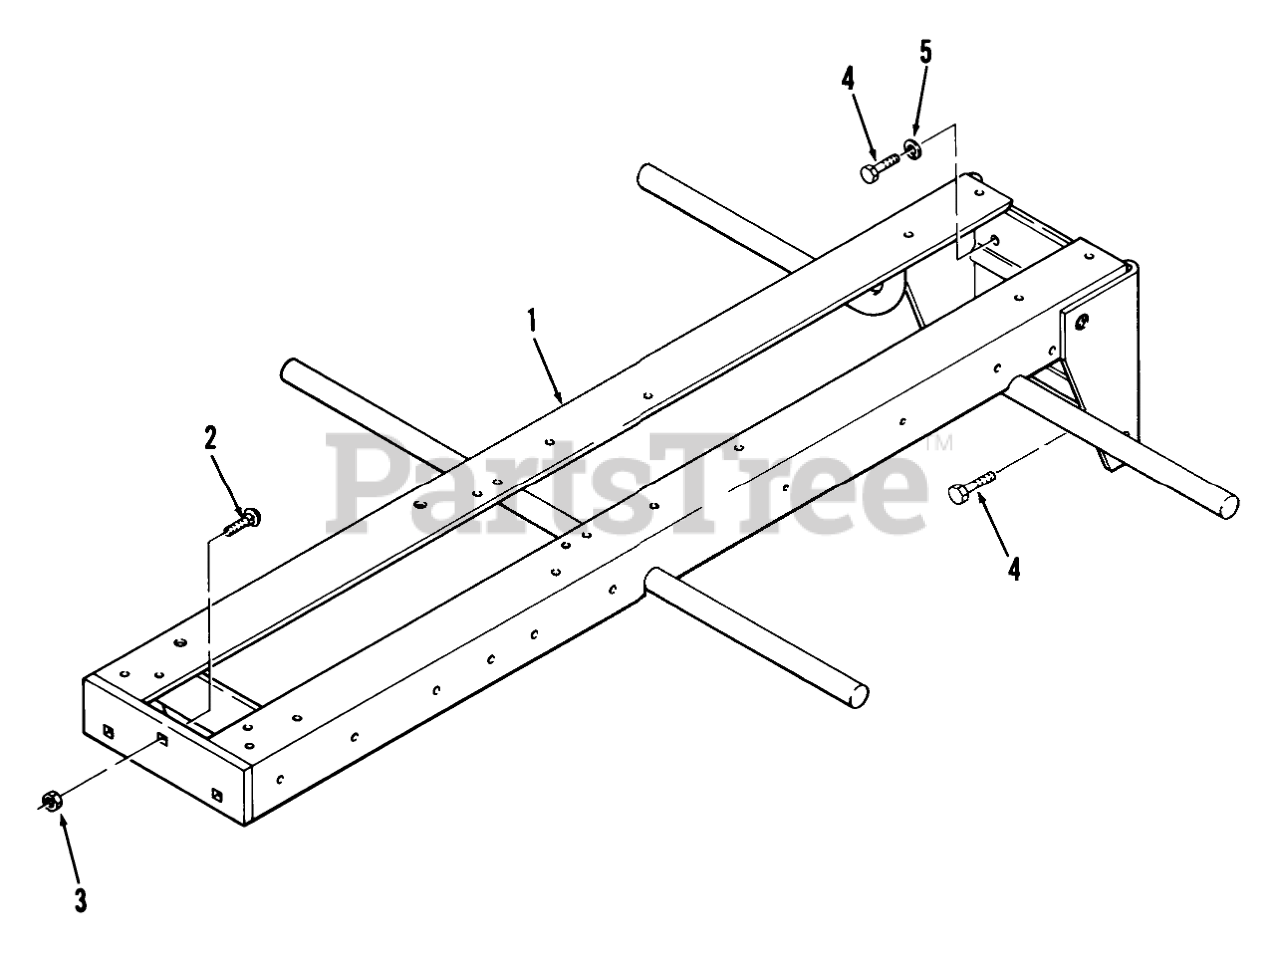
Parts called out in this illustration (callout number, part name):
1	Frame
2	Bolt
3	Nut
4	Bolt
5	LOCKWASHER
